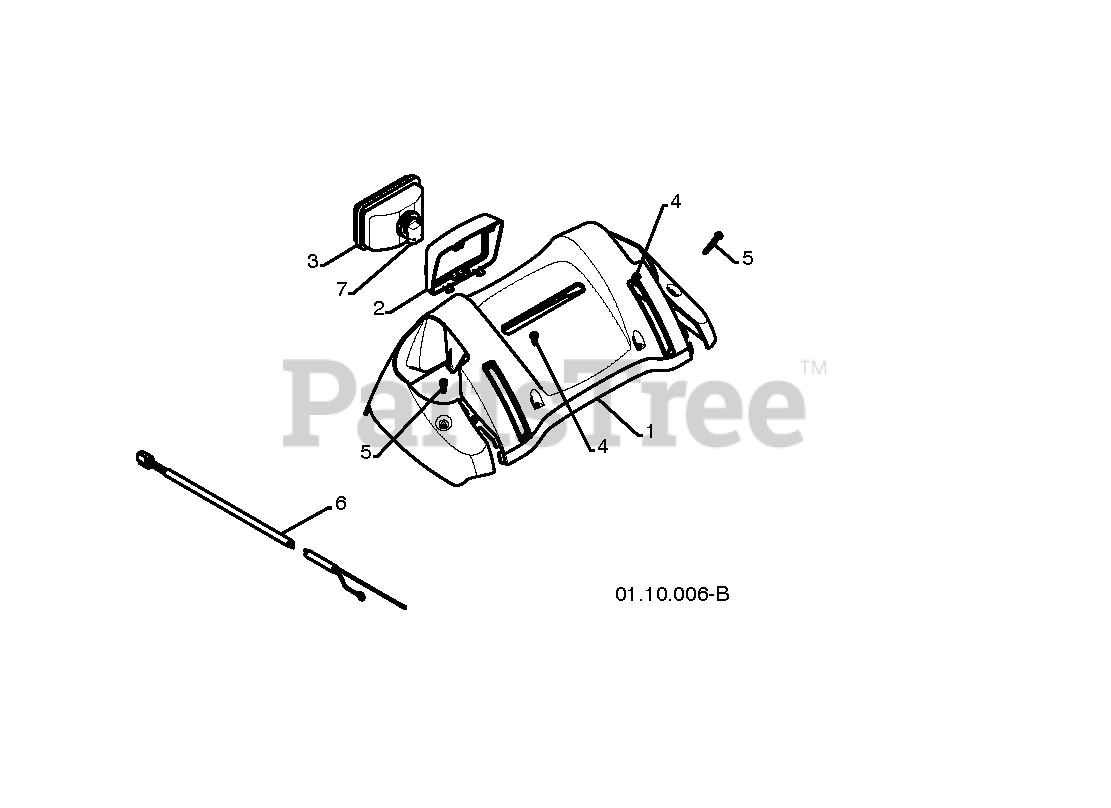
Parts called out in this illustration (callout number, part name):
1	PANEL.CONSOLE.SNOW
2	BEZEL.HEADLIGHT.BLACK
3	HEADLIGHT, HALOGEN
4	SCREW, HEX HEAD, TAPPING
5	SCREW, HEX HD TAPPING #10-24 1
6	HARNESS.WIRE.HALOGEN
7	BULB.HEADLIGHT.HALOGEN.
